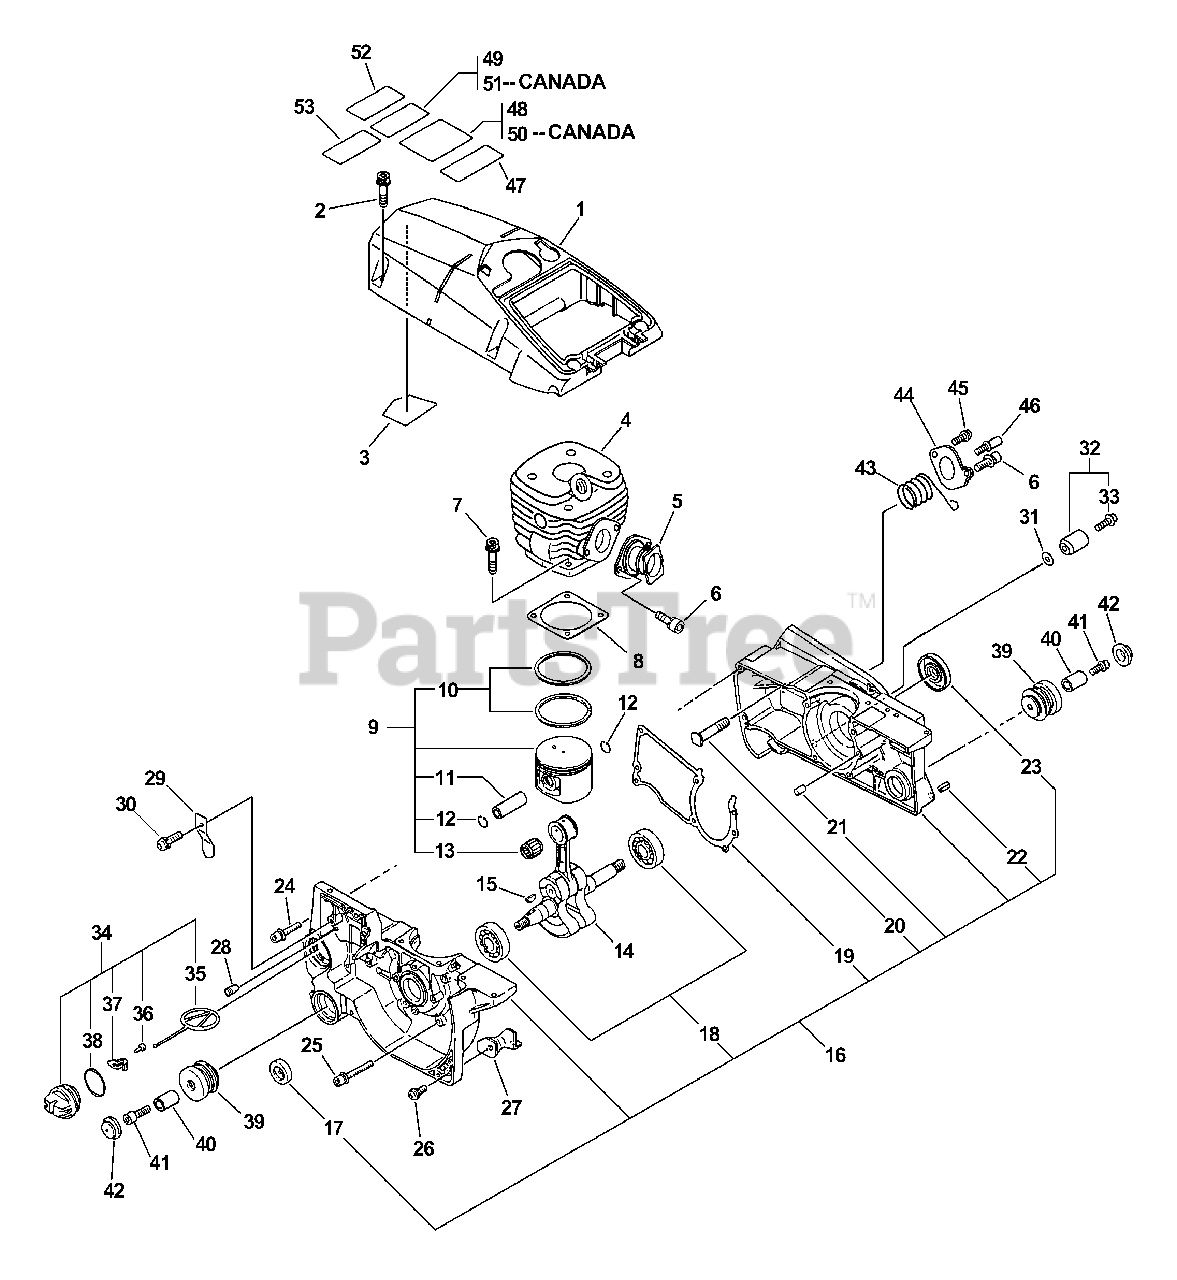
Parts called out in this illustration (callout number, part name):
1	COVER, ENGINE
2	SCREW - 5X20
3	DEFLECTOR, HEAT
4	CYLINDER
5	BELLOWS, INTAKE
6	SCREW - 5X14
7	SCREW - 5X25
8	GASKET, CYLINDER
9	PISTON KIT
10	RING, PISTON
11	PIN, PISTON
12	RING, RETAINING
13	BEARING, NEEDLE
14	CRANKSHAFT ASSY
16	CRANKCASE KIT
17	SEAL, OIL
18	BEARING, BALL - 6202
19	GASKET, CRANKCASE
20	STUD, GUIDE BAR
21	PIN - LOCATING
22	PIN - SPRING -- 5X10
23	SEAL, OIL
24	SCREW - 5X20
25	SCREW - 5X35
26	SCREW - 5X14
27	CUSHION
28	VENT, TANK
30	SCREW - 4X8
31	WASHER - 5
32	CHAIN CATCHER KIT
33	SCREW - 5X18
34	CAP ASSY - ORANGE
35	CONNECTOR, CAP
36	SCREW - 3X8
37	RETAINER
38	O-RING - 25
39	CUSHION
40	COLLAR - 5
41	SCREW - 5X25
42	CAP, CUSHION
45	SCREW - 4X8
46	STUD, THREADED
47	LABEL - KICK BACK
48	LABEL - BAR & CHAIN
49	LABEL - KICK BACK
50	LABEL - BAR & CHAIN
51	LABEL - KICK BACK
52	LABEL - NOISE
53	LABEL - KICK BACK
